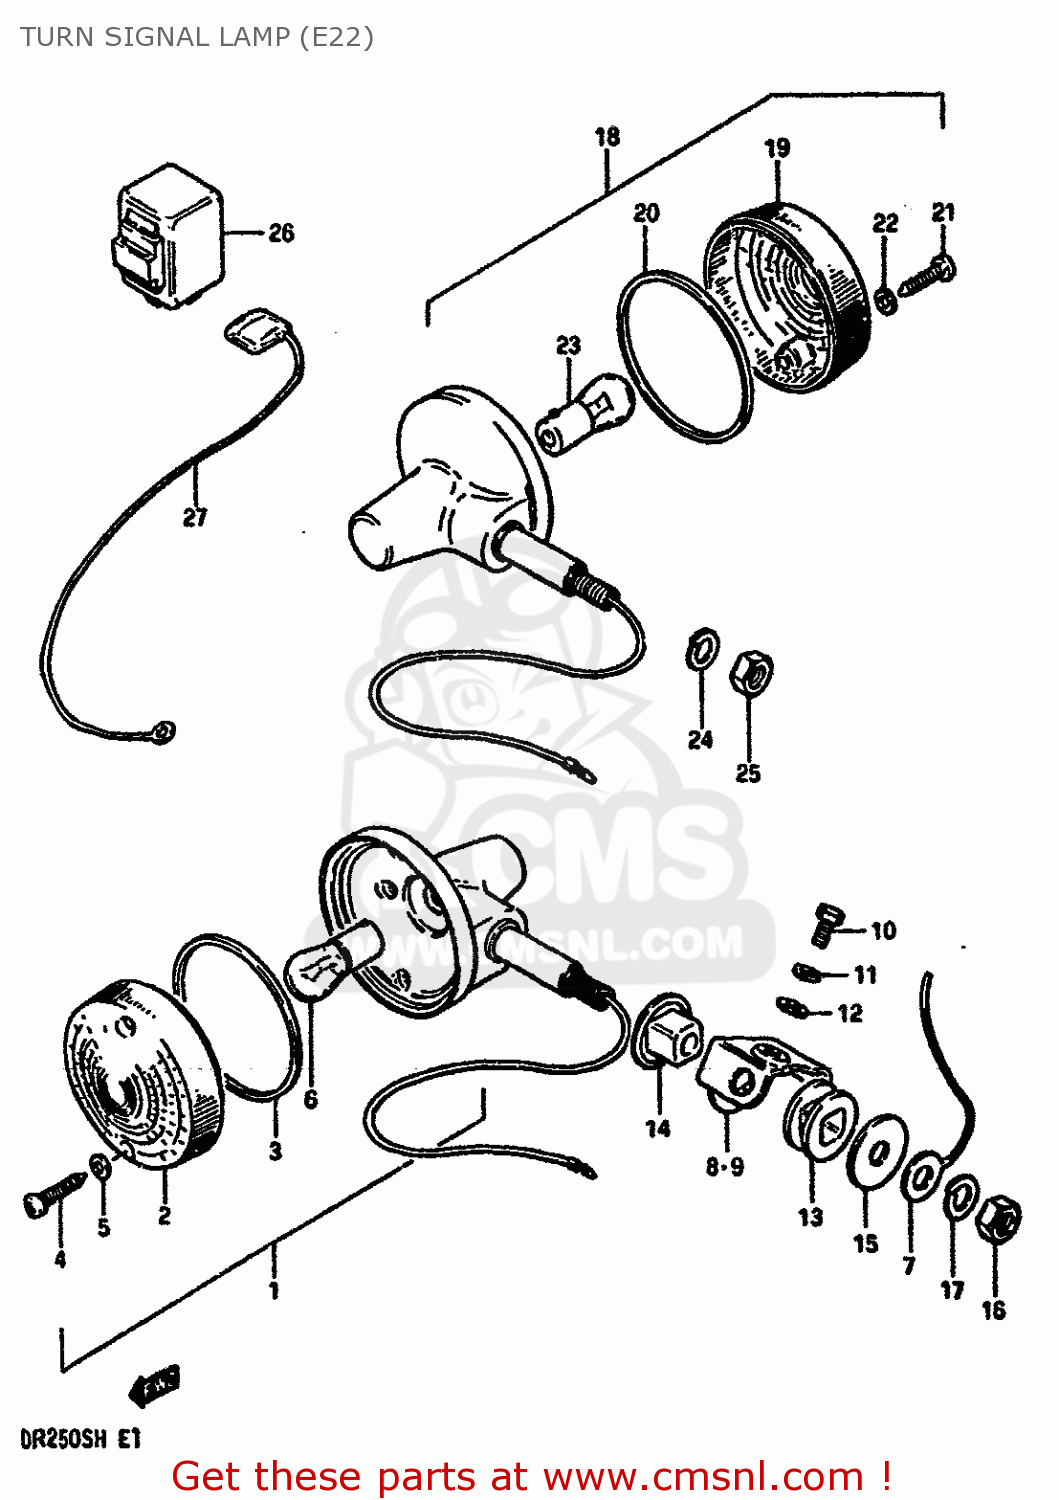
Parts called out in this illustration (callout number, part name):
1	LAMP,FRONT TURN SIGHAL
2	LENS
3	GASKET (NAS)
4	SCREW
5	GASKET (NAS)
6	BULB(12V21W)
7	LEAD WIRE,EARTH
8	BRACKET,TURNSIGNAL LAMP,R
9	BRACKET,TURNSIGNAL LAMP,L
10	BOLT
11	WASHER,LOCK
12	WASHER
13	CUSHION
14	SPACER
15	WASHER (10.5X30X2.3)
16	NUT
17	WASHER,LOCK,10
18	LAMP ASSY,RR TURN SIGNAL
19	LENS,TURN SIGN
20	GASKET (NAS)
21	SCREW
22	GASKET (NAS)
23	BULB(12V21W)
24	LOCK WASHER
25	NUT
26	RELAY ASSY,TUR
27	LEAD WIRE
